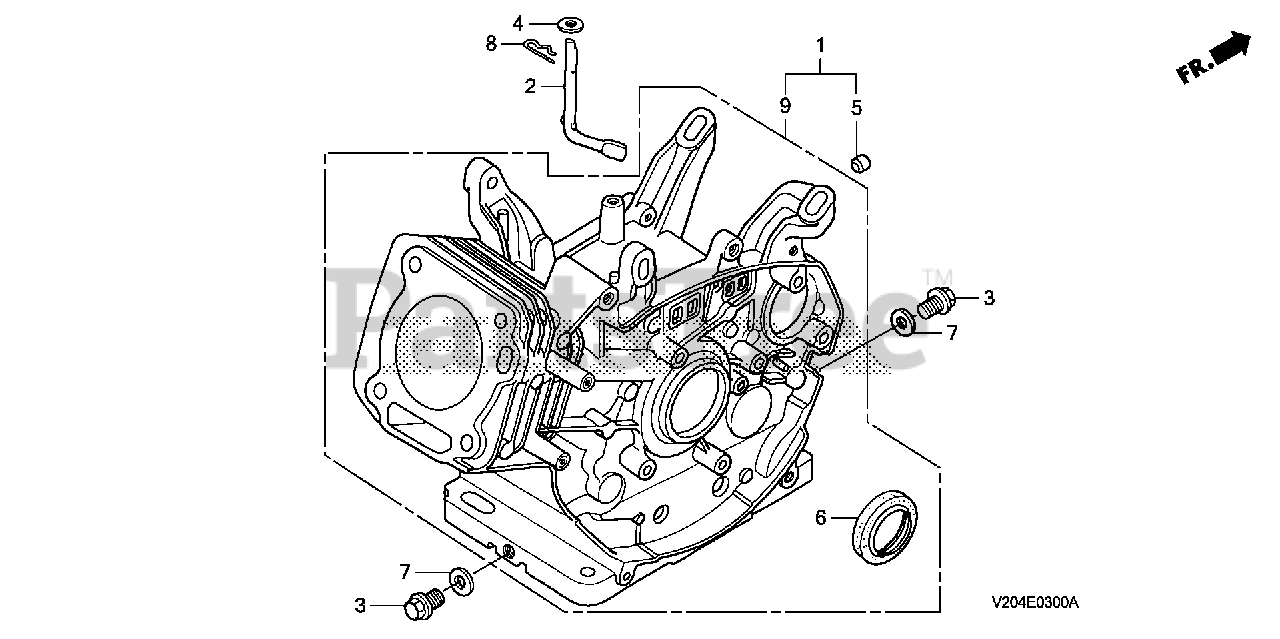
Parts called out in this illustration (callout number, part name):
2	SHAFT, GOVERNOR ARM
3	BOLT, DRAIN PLUG (12X15)
4	WASHER (8.2X17X0.8)
6	OIL SEAL (30X46X8) (NOK ASIA)
7	WASHER, DRAIN PLUG (12MM)
8	PIN, LOCK (10MM)
9	CYLINDER ASSY.
